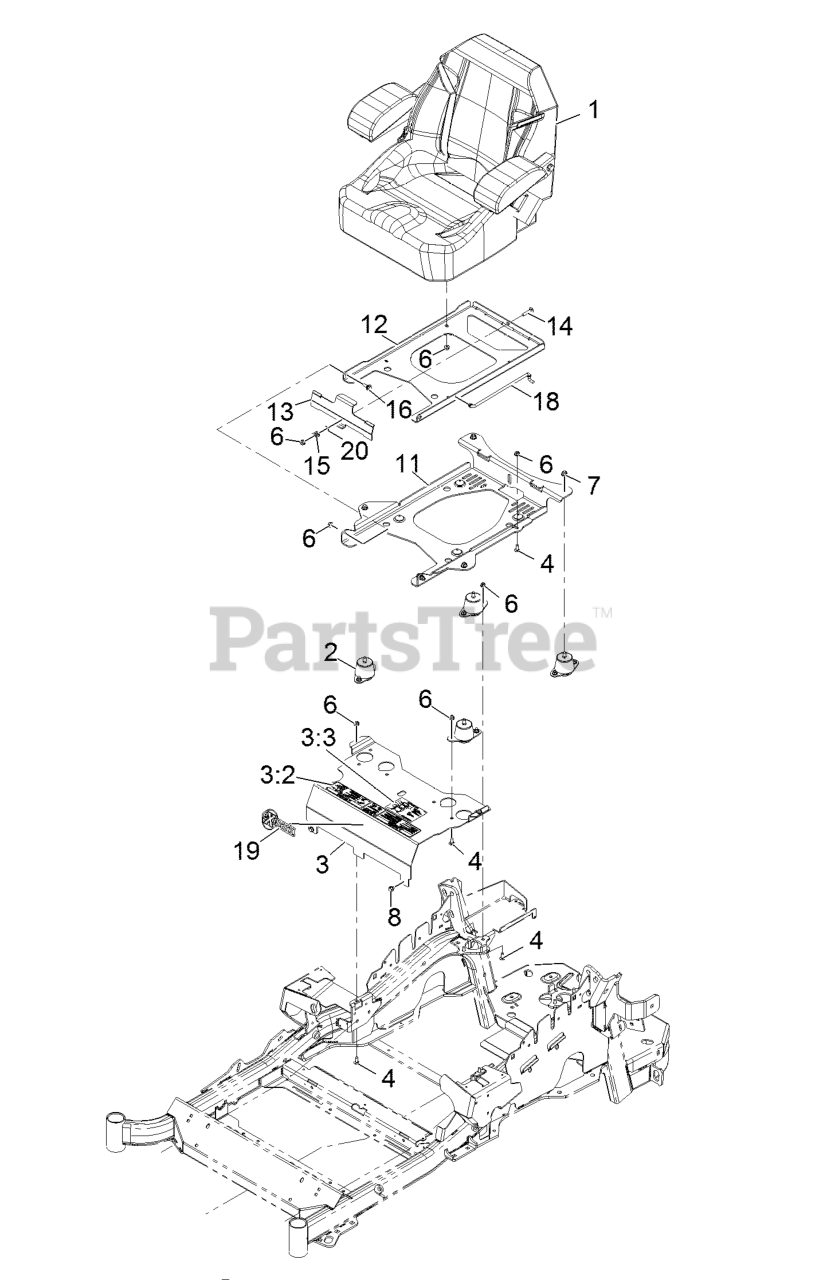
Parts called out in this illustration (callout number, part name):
2	ISOLATOR-SEAT
3	MOUNT-SEAT
3:2	DECAL-CONSOLE
3:3	DECAL-SERVICE AID
4	SCREW-CARR
6	NUT-HF, NI
7	NUT-HF, NI
11	PLATE-TILT, SEAT SUPPORT
12	PLATE-FRAME, SEAT
13	PLATE-LATCH, SEAT
14	BOLT-CARR
15	SPRING-COMPRESSION
16	SCREW-SHOULDER
18	ROD-PROP
20	WASHER-PLAIN
